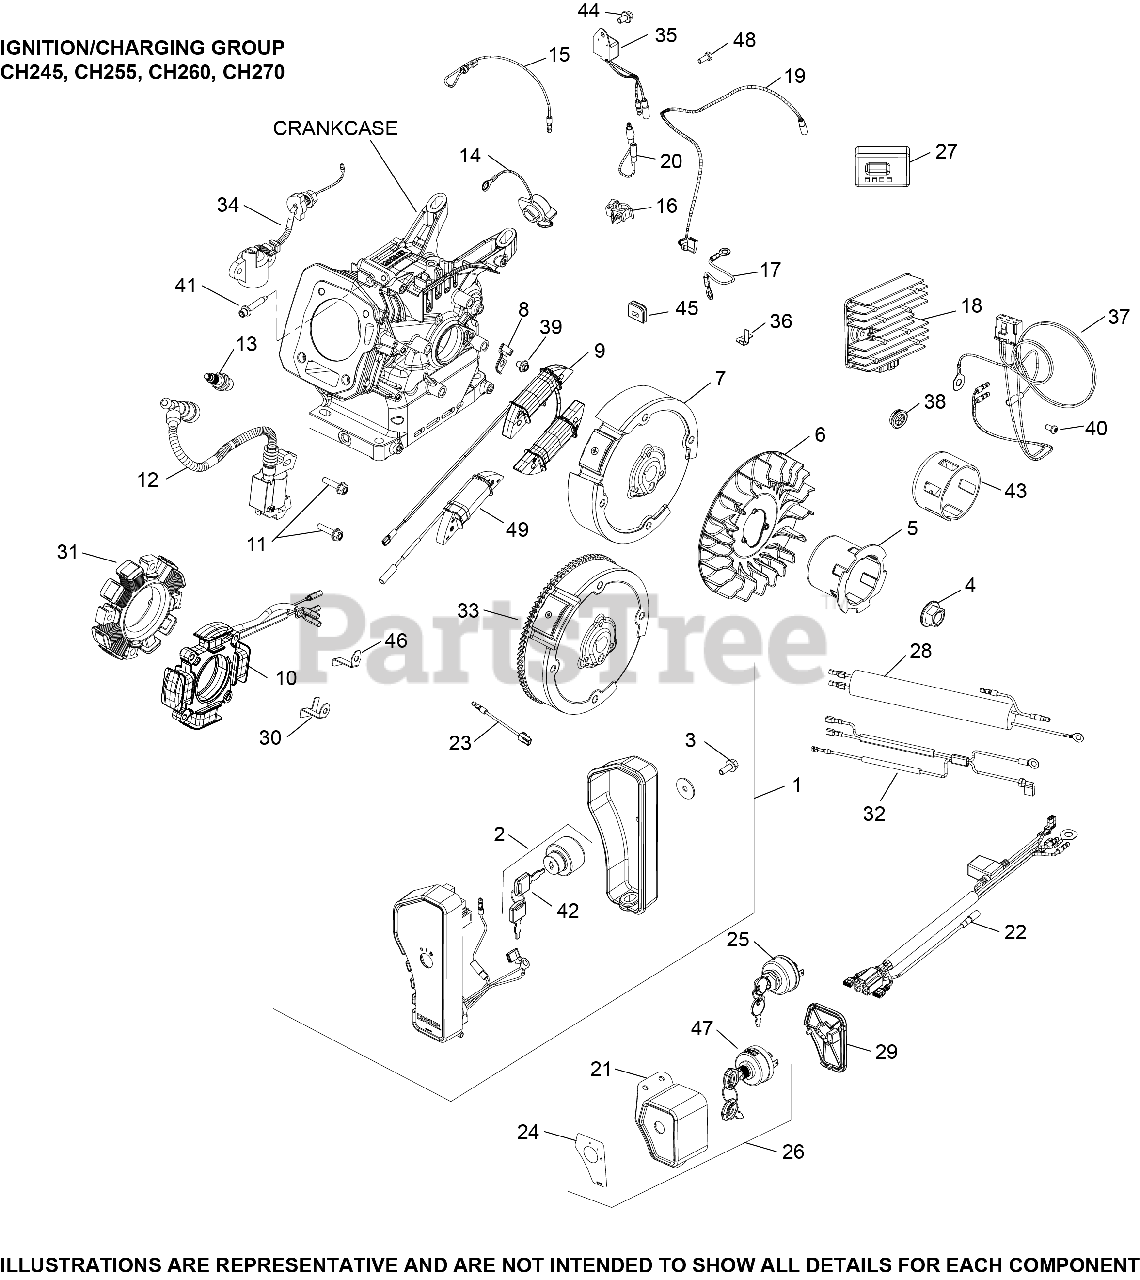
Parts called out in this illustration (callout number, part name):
3	SCREW, HEX FLANGE (M6)-USE 25 086 433-S
4	NUT, FLYWHEEL
5	CUP, STARTER DRIVE
6	FAN, FLYWHEEL
7	FLYWHEEL ASSEMBLY, CAST IRON USE 17 025 28-S
11	SCREW, M6 X 25 USE 25 086 436-S
12	MODULE, IGNITION
13	SPARK PLUG
14	SWITCH, IGNITION
16	CLIP, WIRE HARNESS
19	LEAD, GROUND TO KILL
